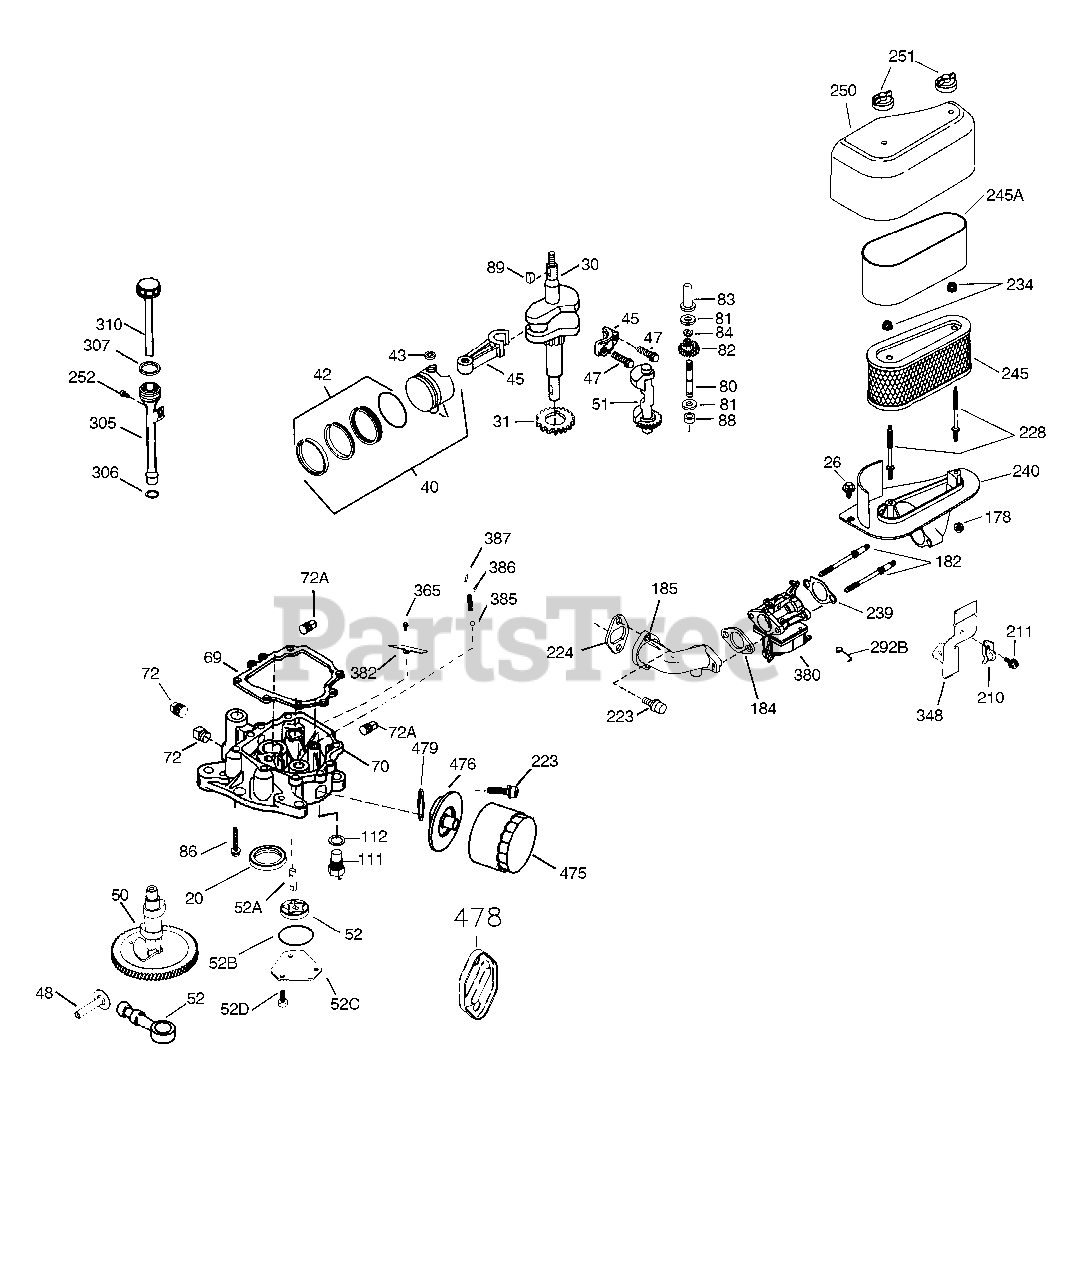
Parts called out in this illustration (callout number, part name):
20	Oil Seal
26	Screw, 1/4-20 x 5/8"
30	Crankshaft
31	Counterbalance Gear
40	Piston, Pin & Ring Set (Std) (Incl. 4 1, 42 & 43)
40	Piston, Pin & Ring Set (.010" OS) (In cl. 41, 42 & 43)
40	Piston, Pin & Ring Set (.020" OS) (In cl. 41, 42 & 43)
41	Piston & Pin Assembly (Std) (Incl. 43 )
41	Piston & Pin Ass'y. (.010" OS) (Incl. 43) 43)
41	Piston & Pin Ass'y. (.020" OS) (Incl. 43) 43)
42	Ring Set (Std.) (3-5/16")
42	Ring Set (.010" OS)
42	Ring Set (.020" OS)
43	Piston Pin Retaining Ring
45	Connecting Rod Ass'y. (Incl. 47)
47	Connecting Rod Bolt
48	Valve Lifter
50	Camshaft (MCR)
51	Counterbalance Weight
52	Oil Pump Assembly
52A	Oil Pump Shaft
52B	* "O" Ring
52C	Oil Pump Cover (Incl. 52B)
52D	Screw, 1/4-20 x 43/64"
69	* Mounting Flange Gasket
70	Mounting Flange (Incl. 72, 72A, 75, 8 0, 381 thru 387) 387)
72	Oil Drain Plug
80	Governor Shaft
81	WASHER
82	Governor Gear Assembly
83	Governor Spool
84	Retaining Ring
86	Screw, 1/4-20 x 1-3/16"
89	Flywheel Key
178	Lock Nut, 1/4-20
182	Carburetor Mounting Stud
184	* Carburetor To Intake Pipe Gasket
185	Intake Pipe
210	Conduit Clip
211	Screw, 10-32 x 3/8"
223	Screw, Torx T-30, 5/16-18 x 1-3/32"
224	* Intake Pipe Gasket
228	Air Cleaner Stud
234	Nut & Lock Washer, 1/4-20
239	* Air Cleaner Gasket
240	Air Cleaner Body (Incl. 239)
245	Air Filter (Incl. 234) also available in Packaged Part #740055B
245A	Poly Pre-Filter (also available in Pa ckaged Part #740055B) also available in Packaged Part #740055B
250	Air Cleaner Cover
251	Wing Nut, 1/4-20
252	Screw, 1/4-20 x 19/32"
266	Screw, 5/16-18 x 1-1/4"
292B	Fuel Line Clamp
305	Oil Fill Tube
306	Fill Tube Gasket
307	"O" Ring
310	Dipstick
365	Screw, 8-32 x 27/64"
380	Carburetor (Incl. 184)
382	Oil Strainer Screen
386	Pressure Relief Spring
387	Roll Pin
394A	Washer
475	Oil Filter
476	Oil Filter Adapter (Incl. 477 & 479)
477	Screw, Torx T-30, 5/16-18 x 1-3/32"
479	* Oil Filter Adapter Gasket
